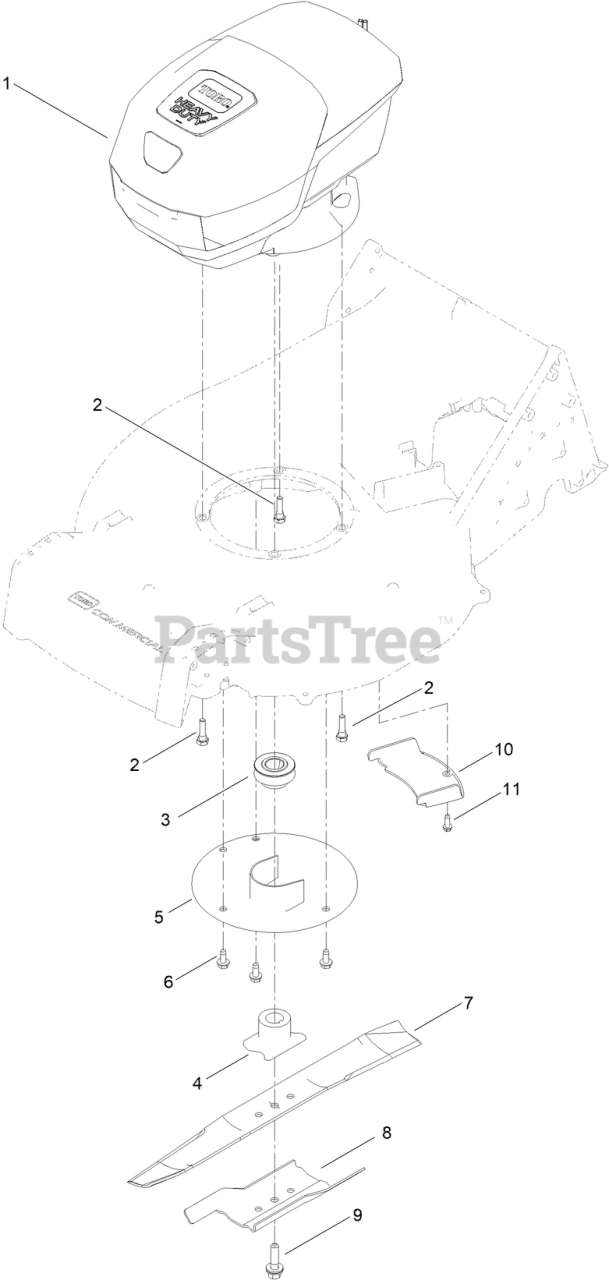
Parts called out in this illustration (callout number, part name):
1	MOTOR MODULE
2	SCREW-TAPTITE
3	PULLEY-DRIVER
4	DRIVER-BLADE
5	PROTECTOR-CRANKSHAFT
6	SCREW-HWHTF
7	BLADE-21IN, RECYCLING
8	ACCELERATOR-BLADE
9	BOLT-BLADE
10	COVER-BELT
11	SCREW-HWHTF
